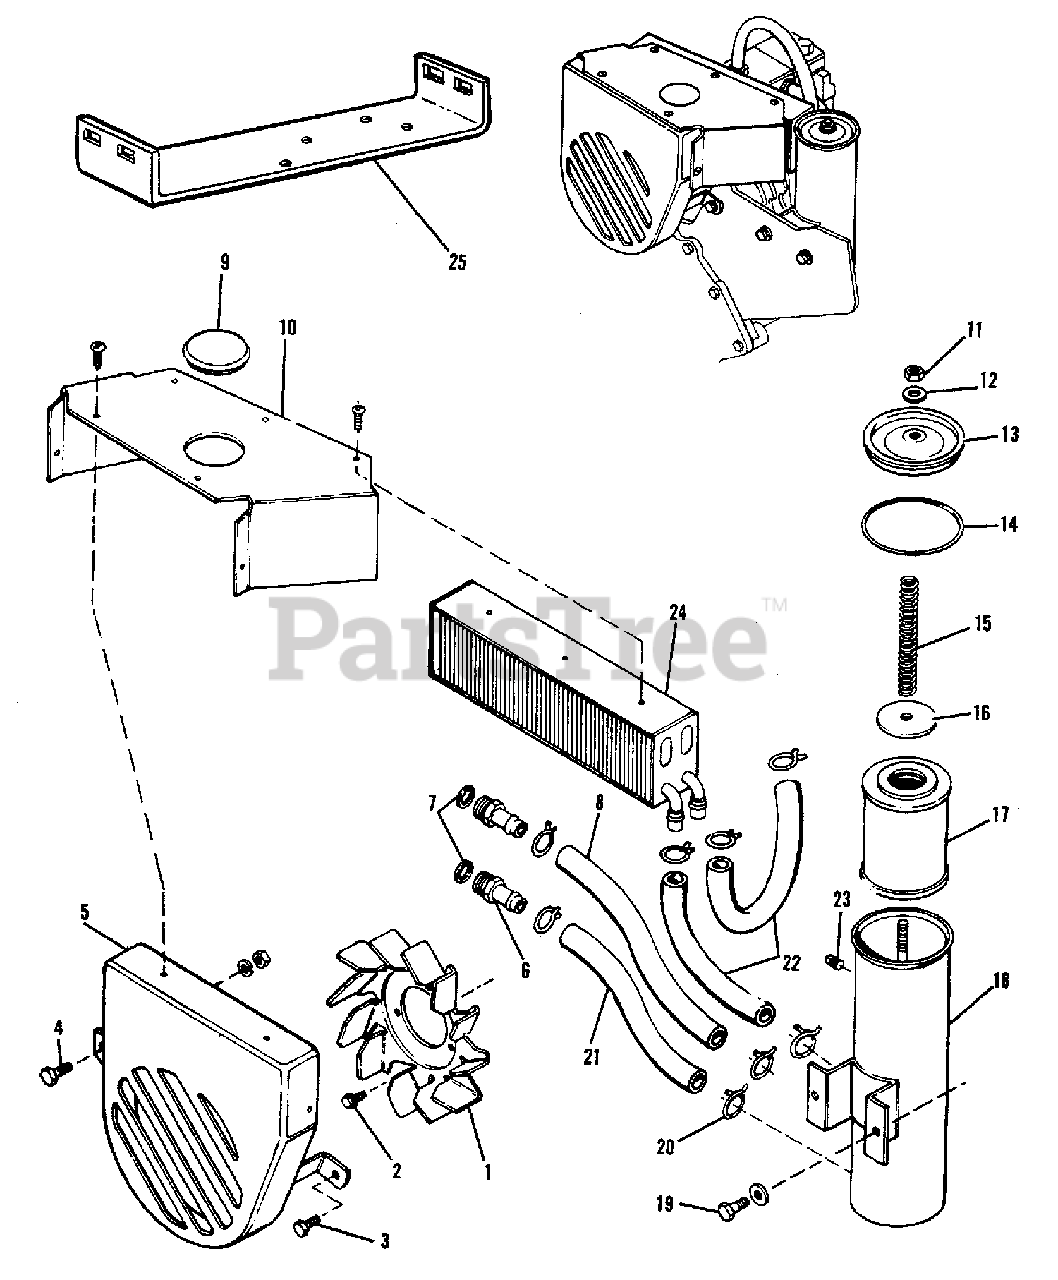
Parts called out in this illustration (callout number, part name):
1	FAN, Pulley
2	SCREW, Washer Head, Tapping, 1/4NC x 1/2
3	SCREW, Self Tapping, 5/16NC x 5/8
4	CAPSCREW, 7/16NC x 4
4	LOCKWASHER, 7/16
4	NUT, 7/16NC
5	SHROUD ASSEMBLY, Fan
6	INSERT, Bead
8	HOSE, Hydraulic
10	DEFLECTOR, Cooler
10	SCREW, Self-Tapping, #10 x 3/8
11	NUT, Esna Lock, 5/16NC
12	WASHER, Nylon
13	COVER, Reservoir
17	ELEMENT, Filter
18	RESERVOIR ASSEMBLY
19	CAPSCREW, Hexagon Head, 5/16NC x 1
19	NUT, Hexagon, 5/16NC
19	LOCKWASHER, 5/16 Medium
19	WASHER, 5/16 Standard
20	CLAMP, Hose
21	HOSE, Hydraulic
22	HOSE, Hydraulic
23	PLUG, 1/4 Square Head, Plastic
24	COOLER, Oil
25	BRACKET, Cooler Support
25	SCREW, Self-Tap, #10 x 3/8
25	SCREW, #10NF x 1/2 (Round Head)
